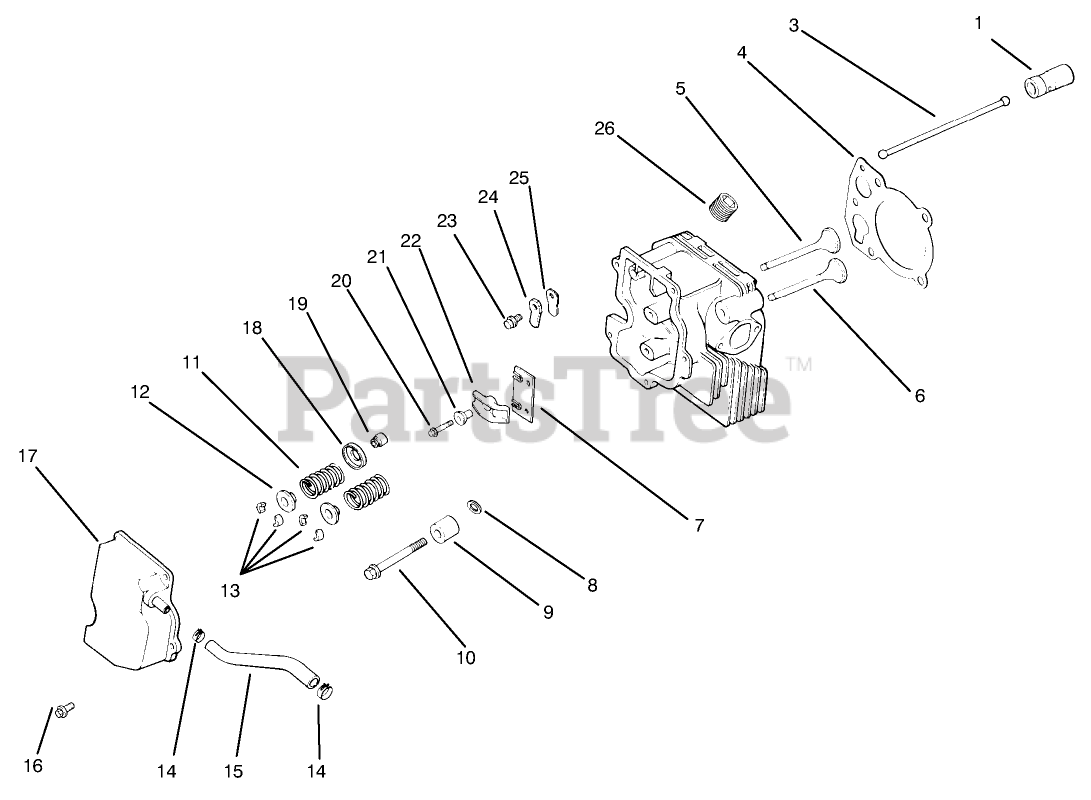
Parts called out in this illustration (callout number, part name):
1	Lifter-Valve
3	Rod-Push
4	Gasket-Cylinder Head
5	Valve-Intake STD
5	Valve-Intake .25
6	Valve-Exhaust STD
6	Valve-Exhaust .25
7	Plate-Guide
8	Washer
9	Spacer-Head Bolt
10	Screw M10x1.5x80
11	Spring-Valve
12	Cap-Spring, Valve
13	Retainer Kit
14	Clamp
15	Hose-Breather
16	Screw
17	Cover-Valve w/Nipple
18	Retainer-Spring
19	Seal-Stem, Valve
20	Screw
21	Pivot-Rocker Arm
22	Arm-Rocker
23	Screw
24	Retainer-Reed
25	Reed-Breather
26	Plug
